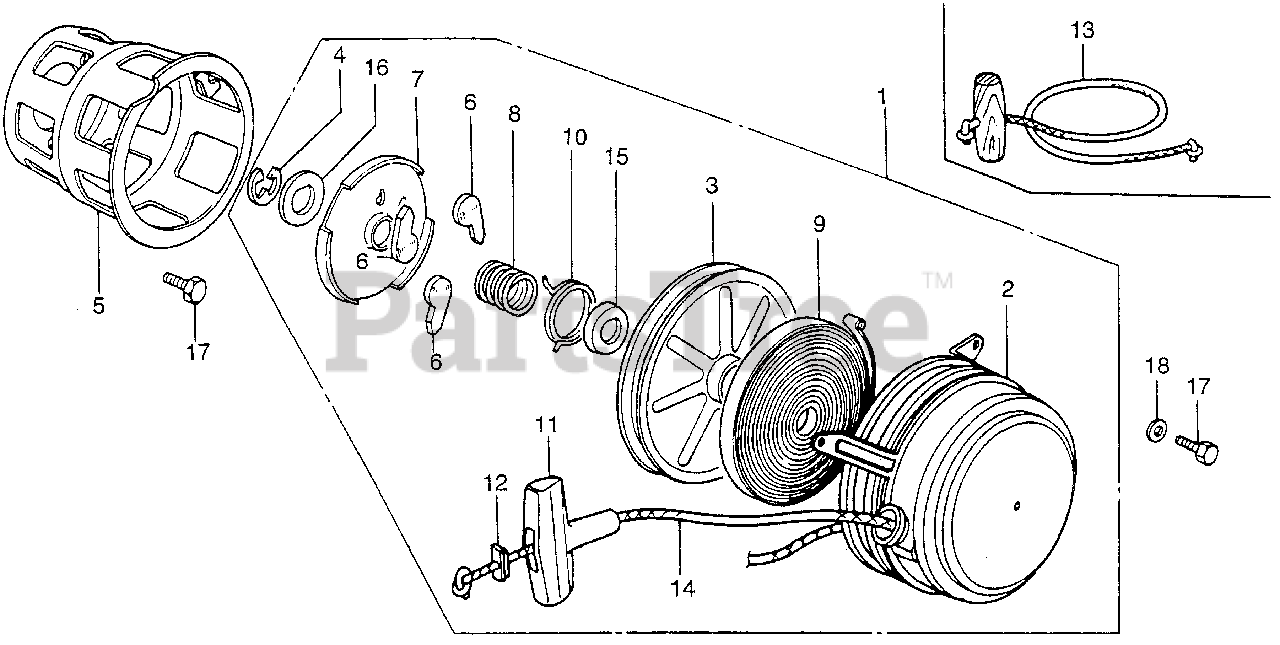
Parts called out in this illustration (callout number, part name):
1	STARTER, RECOIL *R2L* (SCARLET) (NOT AVAILABLE)
2	CASE, STARTER
3	PULLEY, RECOIL STARTER (NOT AVAILABLE)
4	E-RING
5	PULLEY, STARTER
6	RATCHET, STARTER
7	PLATE, FRICTION
8	SPRING, FRICTION
9	SPRING, STARTER RETURN
10	SPRING SET
11	KNOB SET, STARTER
12	STOPPER, ROPE
13	ROPE, STARTER (#6X64") (NOT AVAILABLE)
14	ROPE, STARTER (#6X64")
17	BOLT, HEX. (6X12)
18	WASHER, PLAIN (6MM)
